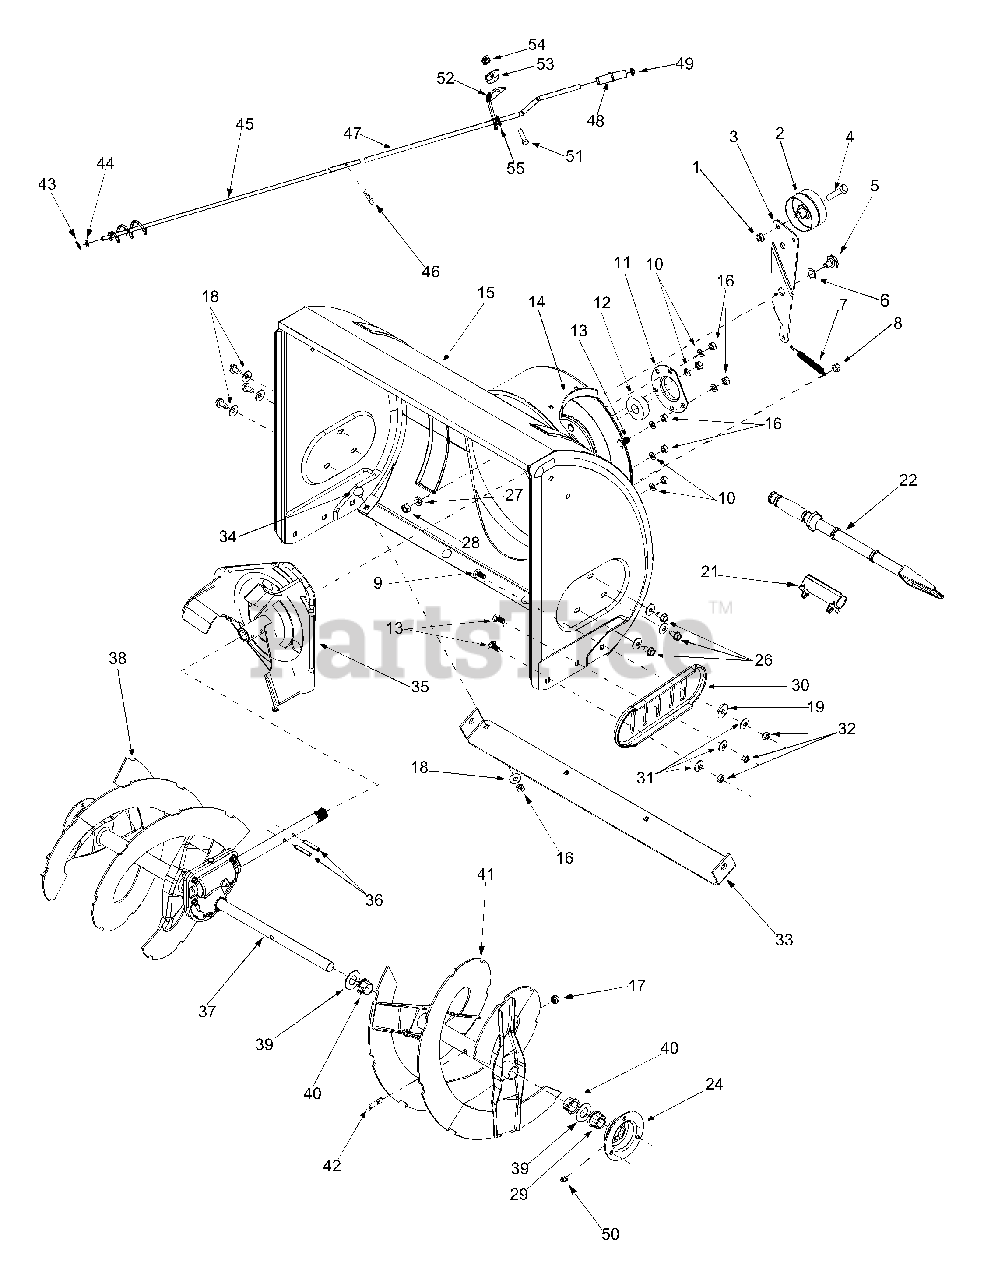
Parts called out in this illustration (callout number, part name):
1	Lock Jam Nut 3/8-24
2	Flat Idler
4	Hex Cap Screw 3/8-24 x 1.50
5	Shoulder Screw
6	Flat Washer.656 ID x 1.25 OD
7	Extension Spring
8	Hex Nut 5/16-18
9	Carriage Bolt, 5/16-18 x 1.00
10	Lock Washer 5/16
12	Ball Bearing
13	Carriage Bolt, 5/16-18 x.75
17	Lock Nut 5/16-18
18	Belleville Washer
19	Flat Wshr,.38ID x 1.38 OD
21	Clean-Out Tool Mount
22	Clean-Out Tool
24	Bearing Housing
26	Hex Screw 5/16-12
27	Lock Washer 3/8
28	Hex Nut 3/8-16
29	Hex Flange Bearing
31	Bell Washer
32	Hex Nut 5/16-18
34	Carriage Bolt 5/16-18 x 1.00
37	Gear Assembly Complete, 28"
39	Flat Washer
40	Flange Bushing
42	Shear Bolt 5/16-18 x 1.5
43	Hairpin Clip
44	Flat Washer
48	Chute Crank Knob
50	Lube Fitting
51	Screw 1/4-20 x.75
53	Bell Washer.265 x.75 x.062
54	Hex Nut 1/4-20
55	Plastic Bushing .380ID
